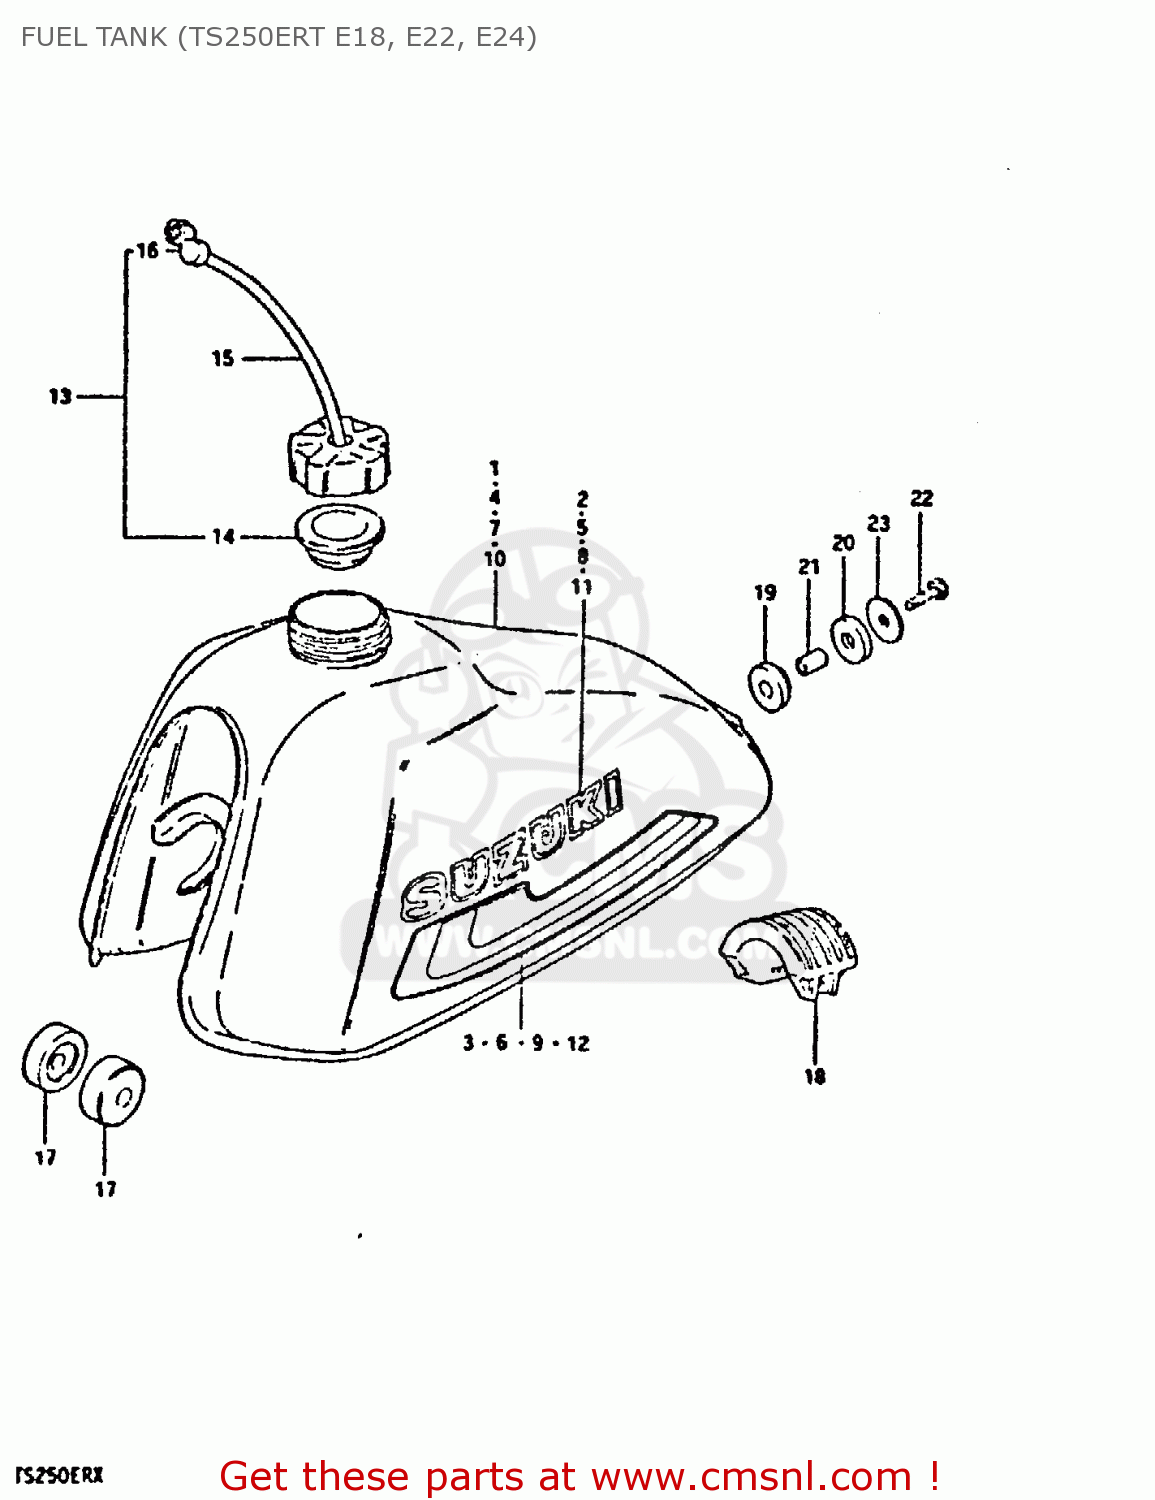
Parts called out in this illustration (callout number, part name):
1	TANK, FUEL (BLUE)
2	EMBLEM,FUEL TANK(WHITE)
3	TAPE SET
4	TANK, FUEL (RED)
5	EMBLEM,FUEL TANK(WHITE)
6	TAPE SET
7	TANK, FUEL (YELLOW)
8	EMBLEM
9	TAPE SET
10	TANK, FUEL (WHITE)
11	EMBLEM
12	TAPE SET
13	CAP SET,FUEL TANK
14	GASKET,FUEL TANK CAP (NAS)
15	HOSE
16	CLAMP,FUEL TANK BREATHER HOSE
17	CUSHION
18	CUSHION,FUEL TANK
19	CUSHION
20	CUSHION
21	SPACER (8.2X12X17)
22	BOLT (8X30)
23	WASHER (8.5X29X1.6)
